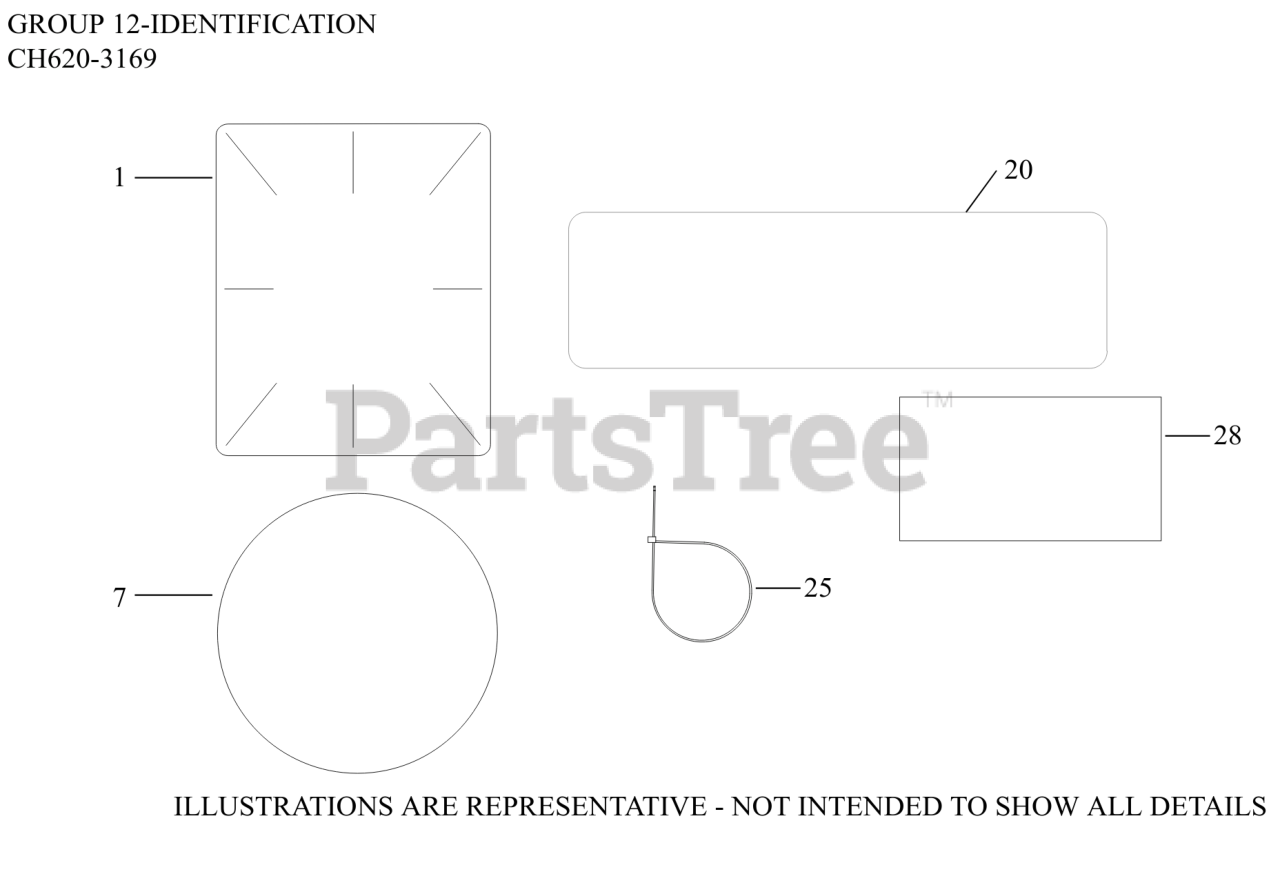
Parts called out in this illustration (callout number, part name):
1	LABEL, CLEAR LAMINATION
7	LABEL, GRASS SCREEN
20	DECAL LPAC, 19 HP/674cc/CV-CH620
28	DECAL, USA
